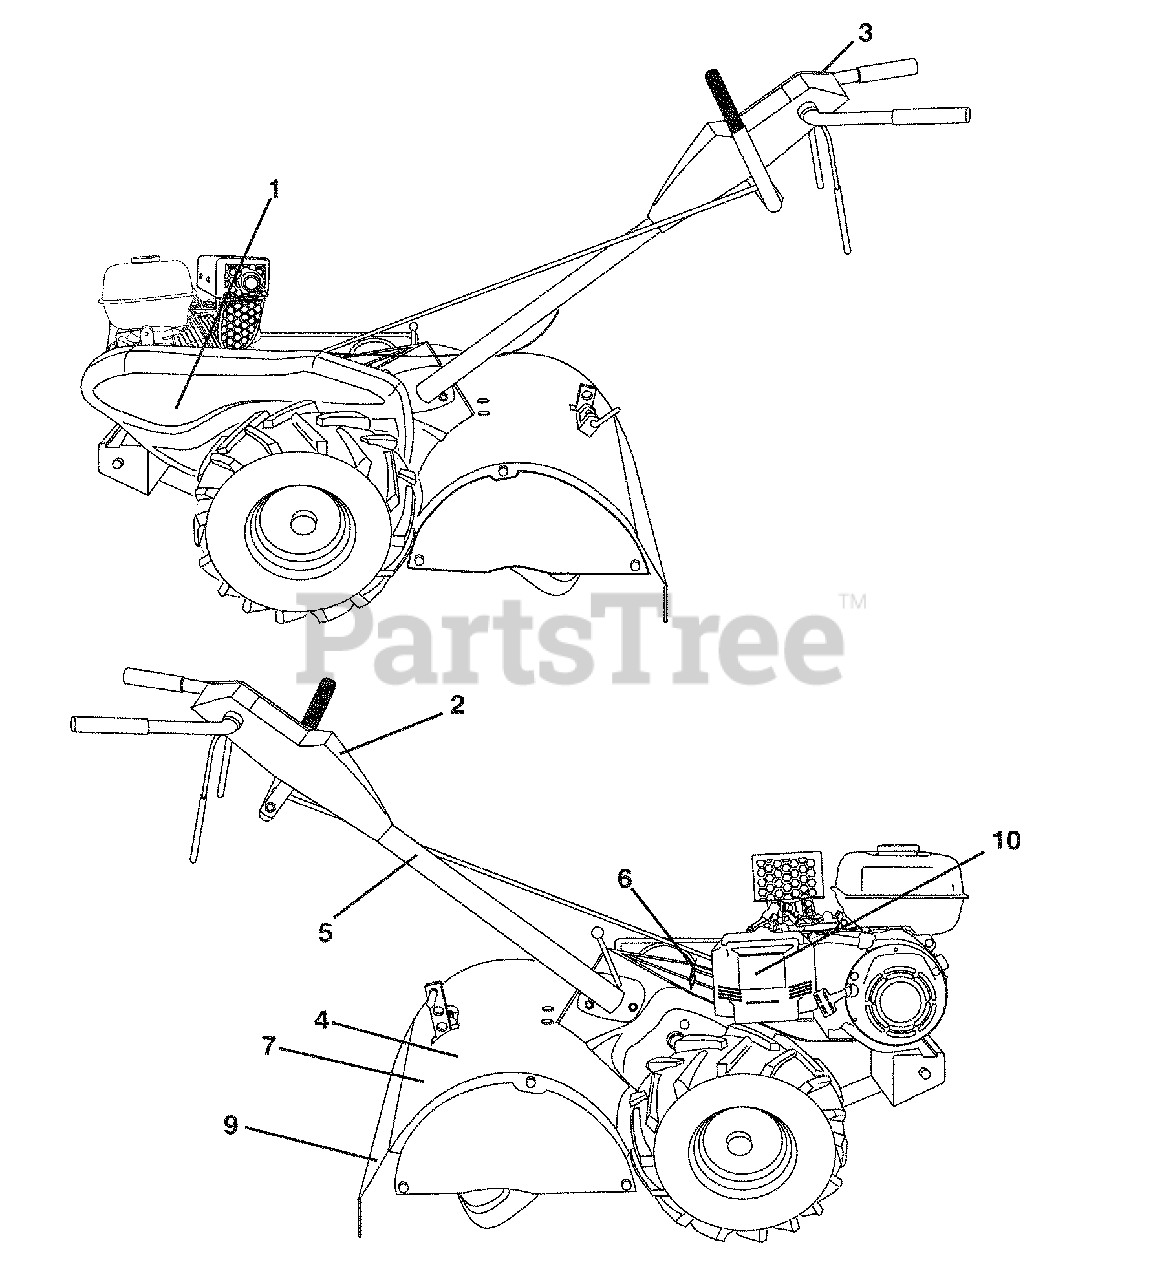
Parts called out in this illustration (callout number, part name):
1	Decal, Belt Guard
2	Decal, Console
3	Decal, Console Instruction
4	Decal, Tine Shield
5	Decal, Hand Placement
6	Decal, Shift Indicator
7	Decal, Warning
9	Decal, Warning, Rotating Tines
10	Decal, Engine, AC
